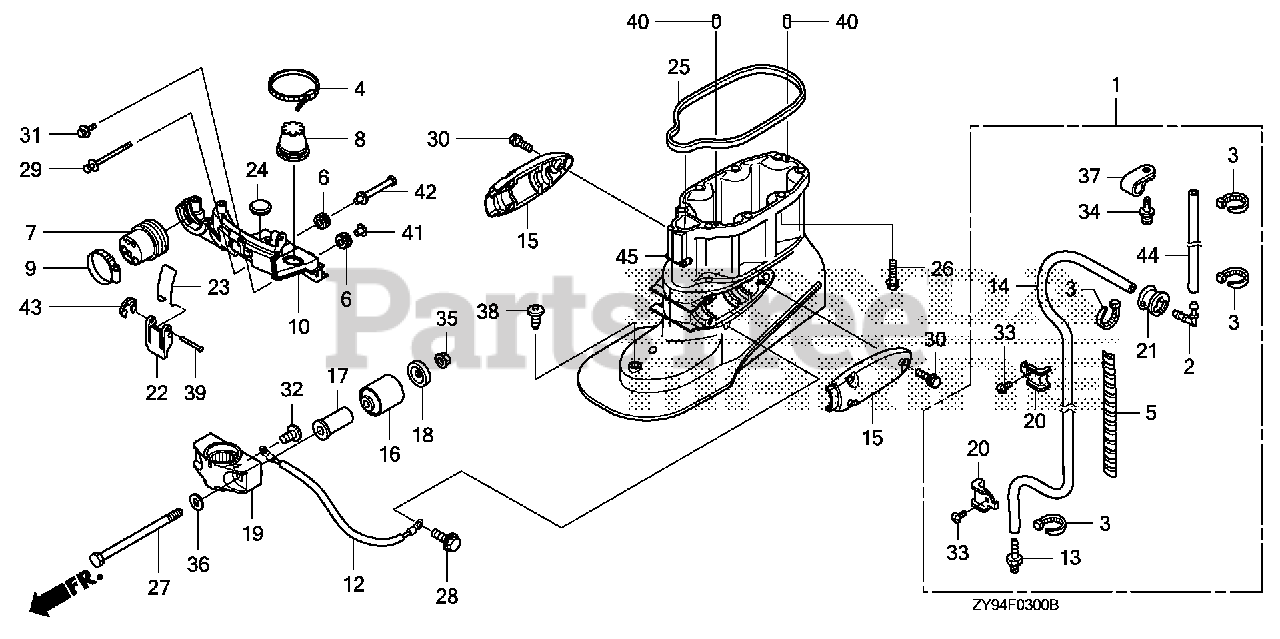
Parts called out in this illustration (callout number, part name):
1	TUBE KIT, SPEED SENSOR
2	JOINT A, BREATHER
3	BAND, WIRE
4	BAND (BLACK 3.5X140)
5	TUBE, SPIRAL
6	GROMMET, CASE (LOWER)
7	GROMMET, HANDLEBAR CABLE
8	GROMMET, CASE (LOWER) (C)
9	BAND, CASE GROMMET (LOWER)
10	BRACKET, FR. COVER (LOWER) *NH282MU* (OYSTER SILVER METALLIC-U)
12	WIRE, LEAD (1.5X137MM)
13	NIPPLE, SENSOR
14	TUBE, SPEED SENSOR
15	HOUSING, MOUNTING (LOWER) *NH282MU* (OYSTER SILVER METALLIC-U)
16	MOUNT, RUBBER (LOWER)
17	COLLAR, MOUNTING (LOWER)
18	STOPPER, MOUNT (LOWER)
19	HOUSING, CENTER MOUNTING (LOWER) *NH282MU* (OYSTER SILVER METALLIC-U)
20	PLATE, SPEED SENSOR TUBE
21	BUSH, MOTOR CODE
22	LEVER, FASTENER
23	WIRE, FASTENER
24	CAP, L. SIDE COVER
25	SEAL B, COVER (LOWER)
26	BOLT, FLANGE (10X40)
27	BOLT, HEX. (12X186)
28	BOLT, FLANGE (6X12)
29	BOLT-WASHER (6X95)
30	BOLT-WASHER (8X30)
31	BOLT-WASHER (6X27)
32	SCREW, PAN (6X8)
33	SCREW, PAN (6X8)
34	SCREW, RIVET (5X10)
35	NUT, FLANGE (12MM)
36	WASHER, PLAIN (12MM)
37	CLIP (14MM)
38	CLIP (7MM)
38	CLIP, FLOOR LID (7MM)
39	PIN (5X44.5)
40	PIN, DOWEL (6X10)
41	COLLAR, MODULE IGNITION CONTROL CASE (CDI)
42	COLLAR, FR. BRACKET
43	E-RING (4MM)
44	BULK HOSE, VACUUM (5X3000) (5X950)
45	CASE, EXTENSION *NH282MU* (OYSTER SILVER METALLIC-U)
